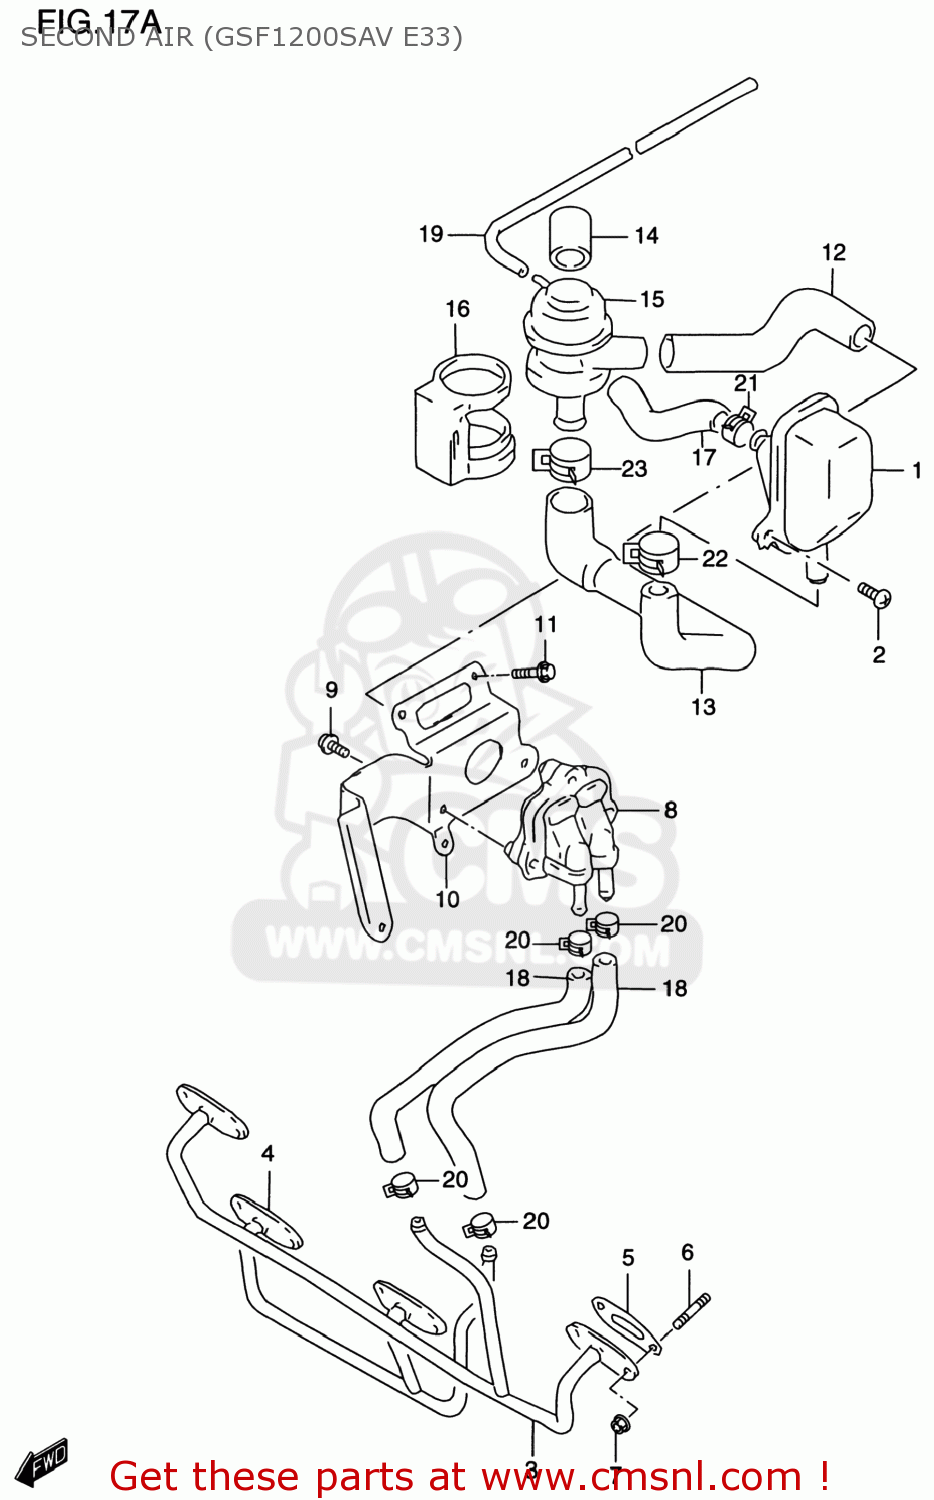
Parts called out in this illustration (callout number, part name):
1	CLEANER ASSY,2ND AIR
2	SCREW
3	PIPE COMP,SECOND AIR,OUTER
4	PIPE COMP,SECOND AIR,INNER
5	GASKET,SECOND AIR PIPE (NAS)
6	STUD BOLT
7	NUT
8	VALVE ASSY,2ND AIR REED
9	BOLT
10	BRACKET COMP,REED VALVE
11	BOLT
12	HOSE,SECOND AIR SWITCH VALVE
13	HOSE,SECOND AIR CLEANER
14	CAP,SWITCHING VALVE
15	VALVE ASSEMBLY,SECOND AIR SWITCH
16	CUSHION,2ND AIR VALVE
17	HOSE,SECOND AIR CLEANER INLET
18	HOSE(9X14X600)
19	HOSE(4X7X600)
20	CLIP
21	CLIP
22	CLIP
23	CLIP
